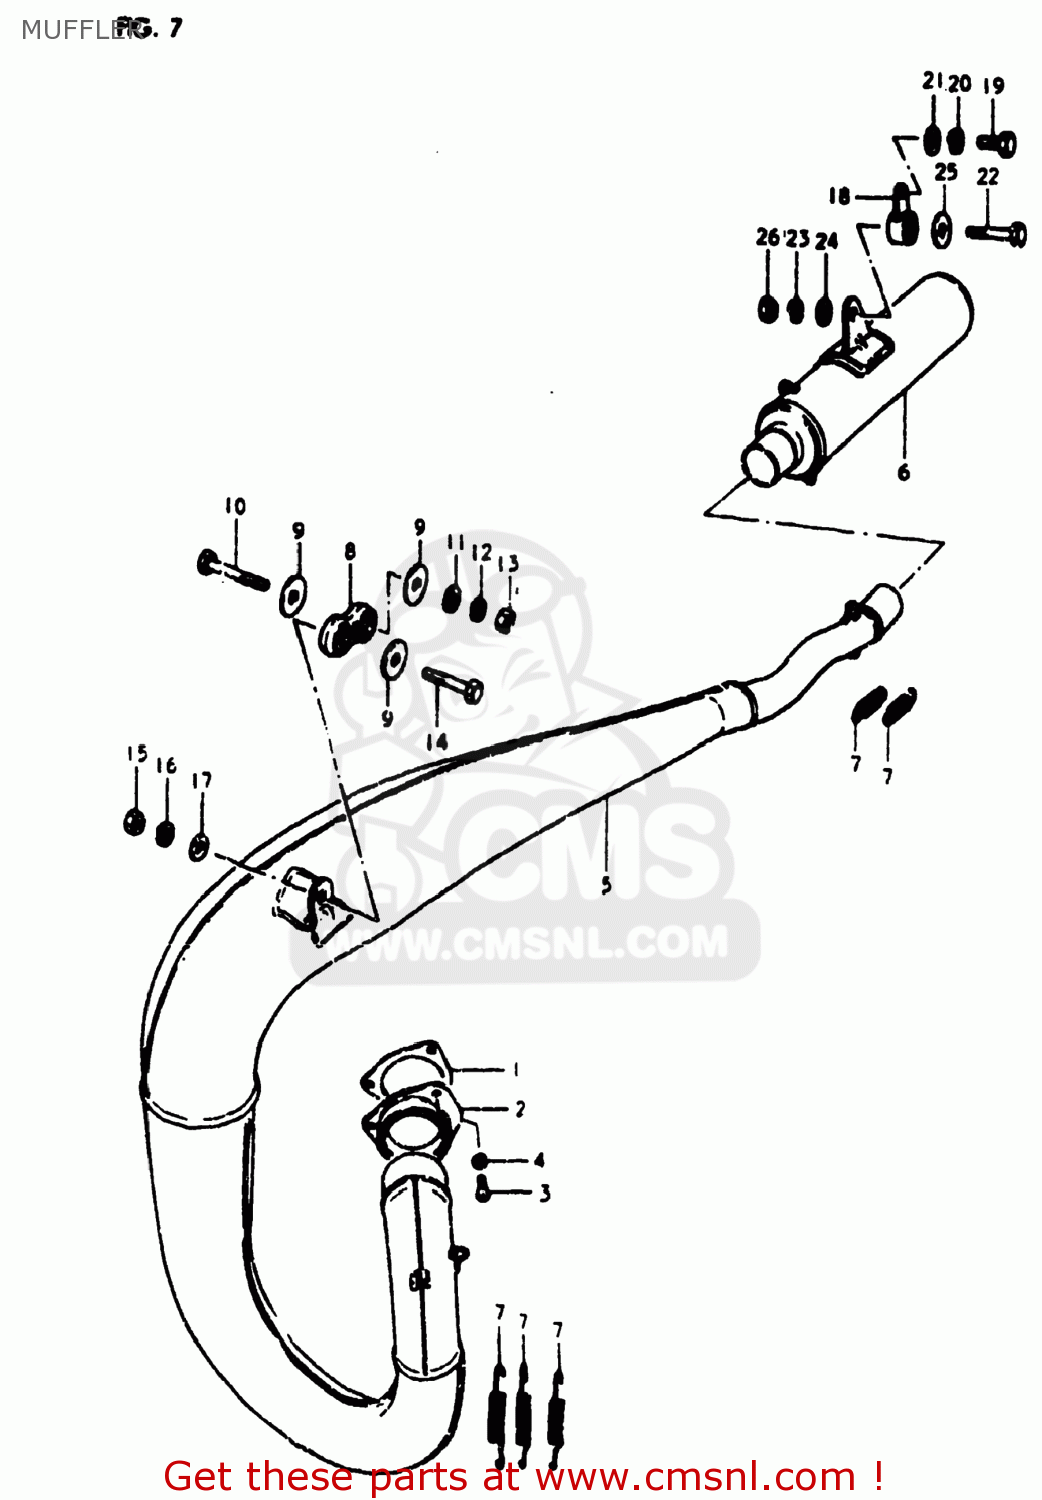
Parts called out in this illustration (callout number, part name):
1	GASKET,EXHAUST PIPE (MCA)
2	FLANGE,EXHAUST PIPE
3	SCREW
4	LOCK WASHER
5	BODY,MUFFLER
6	BODY,MUFFLER
7	SPRING
8	DAMPER,MUFFLER
9	WASHER
10	BOLT
11	WASHER
12	LOCK WASHER
13	NUT
14	BOLT
15	NUT
16	LOCK WASHER
17	WASHER
18	DAMPER,MUFFLER SUPPORT
19	BOLT
20	LOCK WASHER
21	WASHER
22	BOLT
23	LOCK WASHER
24	WASHER
25	WASHER (8.5X29X1.6)
26	NUT
